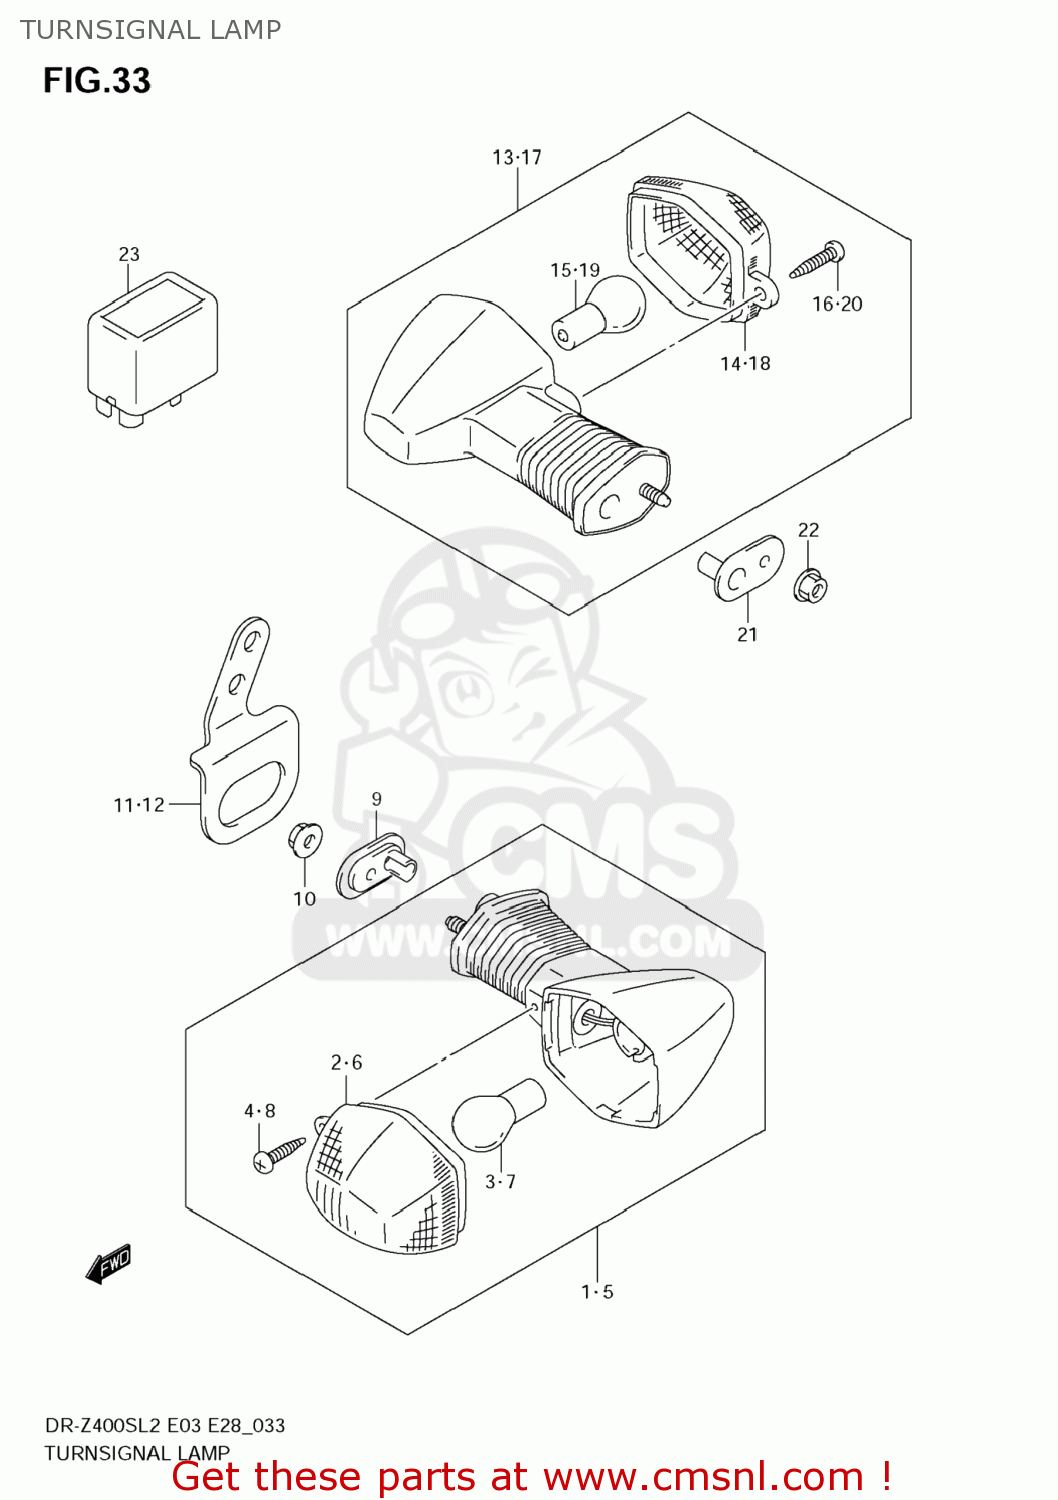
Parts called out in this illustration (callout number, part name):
1	LAMP ASSY,FR TURN SIGNAL,R
2	LENS
3	BULB(12V21W,AMBER)
4	SCREW
5	LAMP ASSY,FR TURN SIGNAL,L
6	LENS
7	BULB(12V21W,AMBER)
8	SCREW
9	PLATE,TURNSIGNAL LAMP
10	NUT
11	BRACKET,FR TURNSIGNAL,R
12	BRACKET,FR TURNSIGNAL,L
13	LAMP ASSY,RR TURNSIGNAL,R
14	LENS
15	BULB(12V21W,AMBER)
16	SCREW
17	LAMP ASSY,RR TURNSIGNAL,L
18	LENS
19	BULB(12V21W,AMBER)
20	SCREW
21	PLATE,TURNSIGNAL LAMP
22	NUT
23	RELAY ASSY,TURNSIGNAL LAMP
